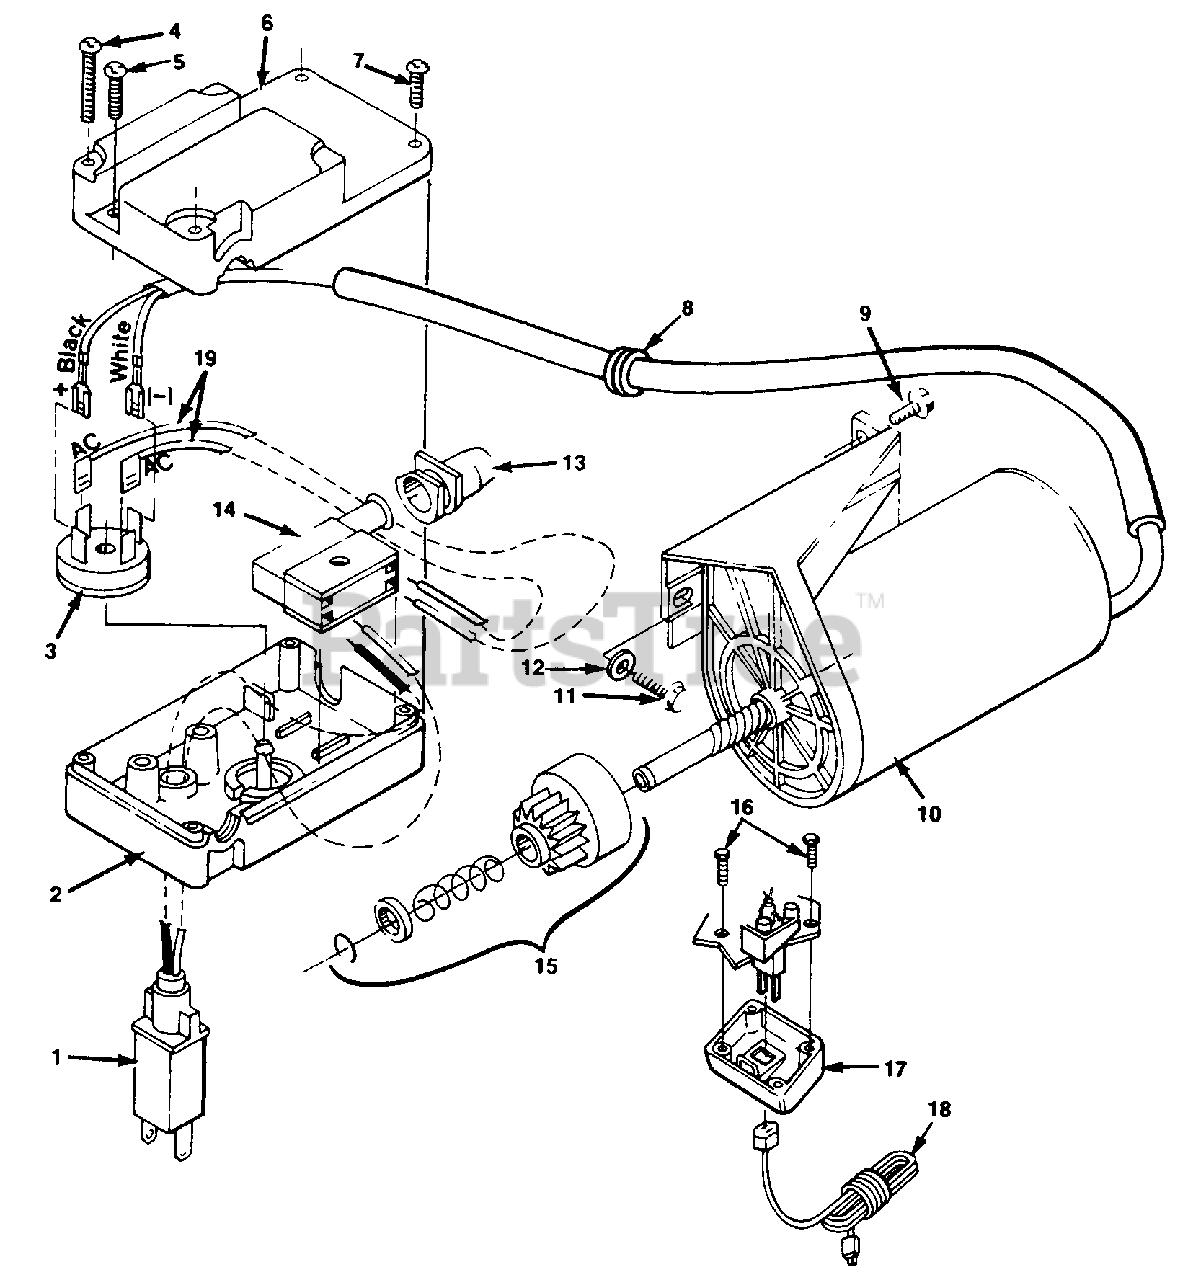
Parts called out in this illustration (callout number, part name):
1	PLUG-Electrical
2	HOUSING-Electrical start
3	RECTIFIER
4	SCREW-Thd. forming 8 x 1 1/4"
5	SCREW-Thd. forming
6	COVER-Electric start
7	SCREW-Thd. forming 8 x 1/2
8	GROMMET
9	SCREW-Thd. forming 10-24 x 3/4
10	MOTOR- Pinion end plate
11	SCREW-Thd. forming 12-24 x 5/8
13	BOOT-Switch
14	SWITCH-Electric starter
16	SCREW 10 x 3/4"
17	COVER-Starter
19	LEAD- Electrical
